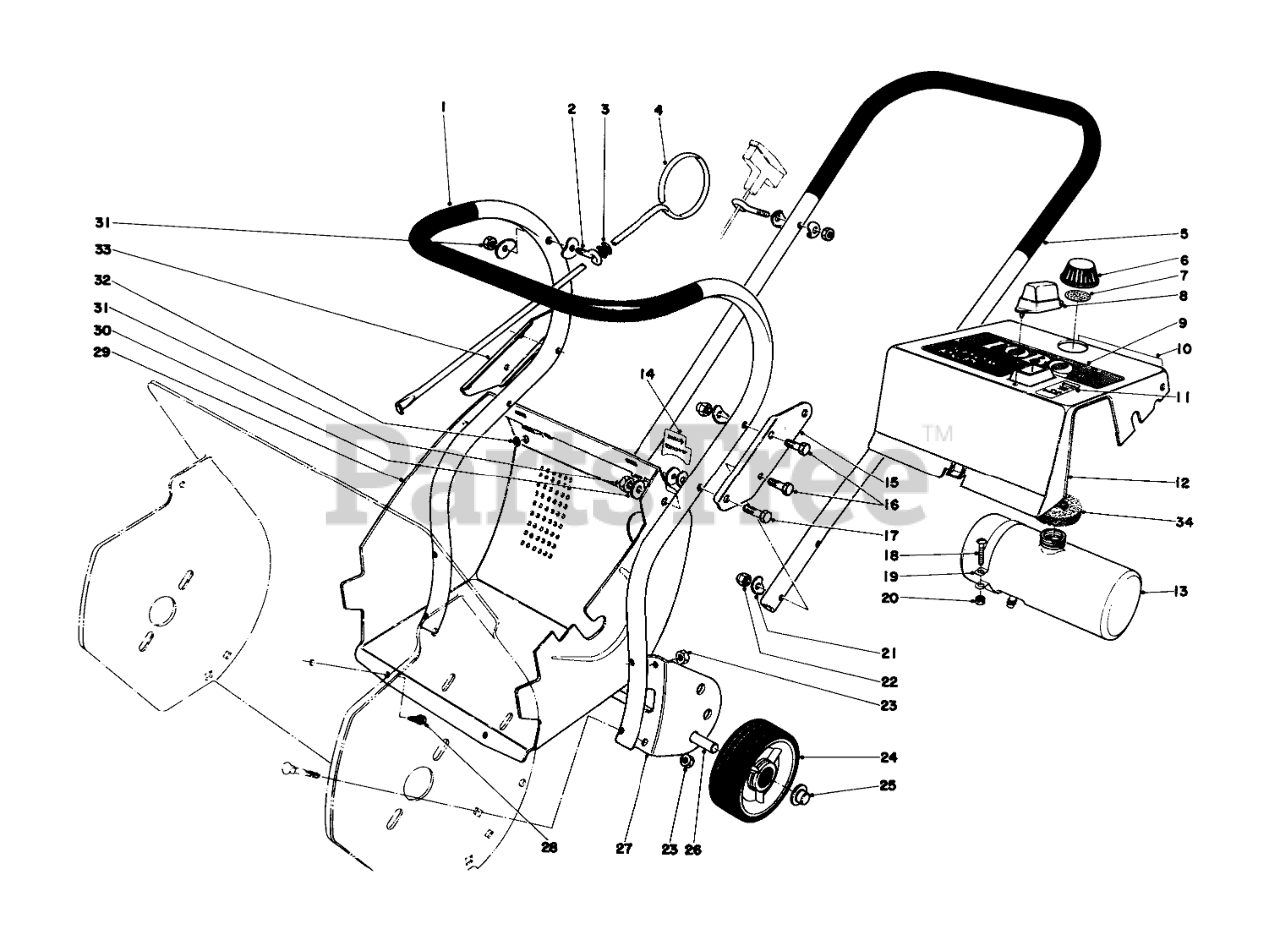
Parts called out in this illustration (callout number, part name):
1	Lower Handle
2	Bolt-Eye
3	GROMMET
4	Vane Adj. Rod
5	Upper Handle
6	Gas Cap (Incl. Ref. #7)
7	GAS CAP GASKET
9	Decal
10	Decal-Fuel Mix
11	Decal
12	Shroud Upper (Incl. Ref. #8-11)
13	Gas Tank Assembly (Incl. Ref. #6 & 7)
14	Decal
15	SPLICE PLATE
16	SCREW-HH
17	SCREW-HH
18	10-24 X 1 RND HD MS
19	1/2 GAS TANK CLAMP
20	NUT-SQ
21	WASHER
22	NUT-CAP
23	NUT-HEX
24	Wheel
25	RETAINER-PUSH ON
27	Wheel Bracket
28	SCREW-HWHTF
29	Lower Shroud (Incl. Ref. #32)
30	WASHER-FLAT
31	NUT-LOCK
32	SNO PUP PLATED EYELET
33	Plate-Splice
34	FOAM PAD
